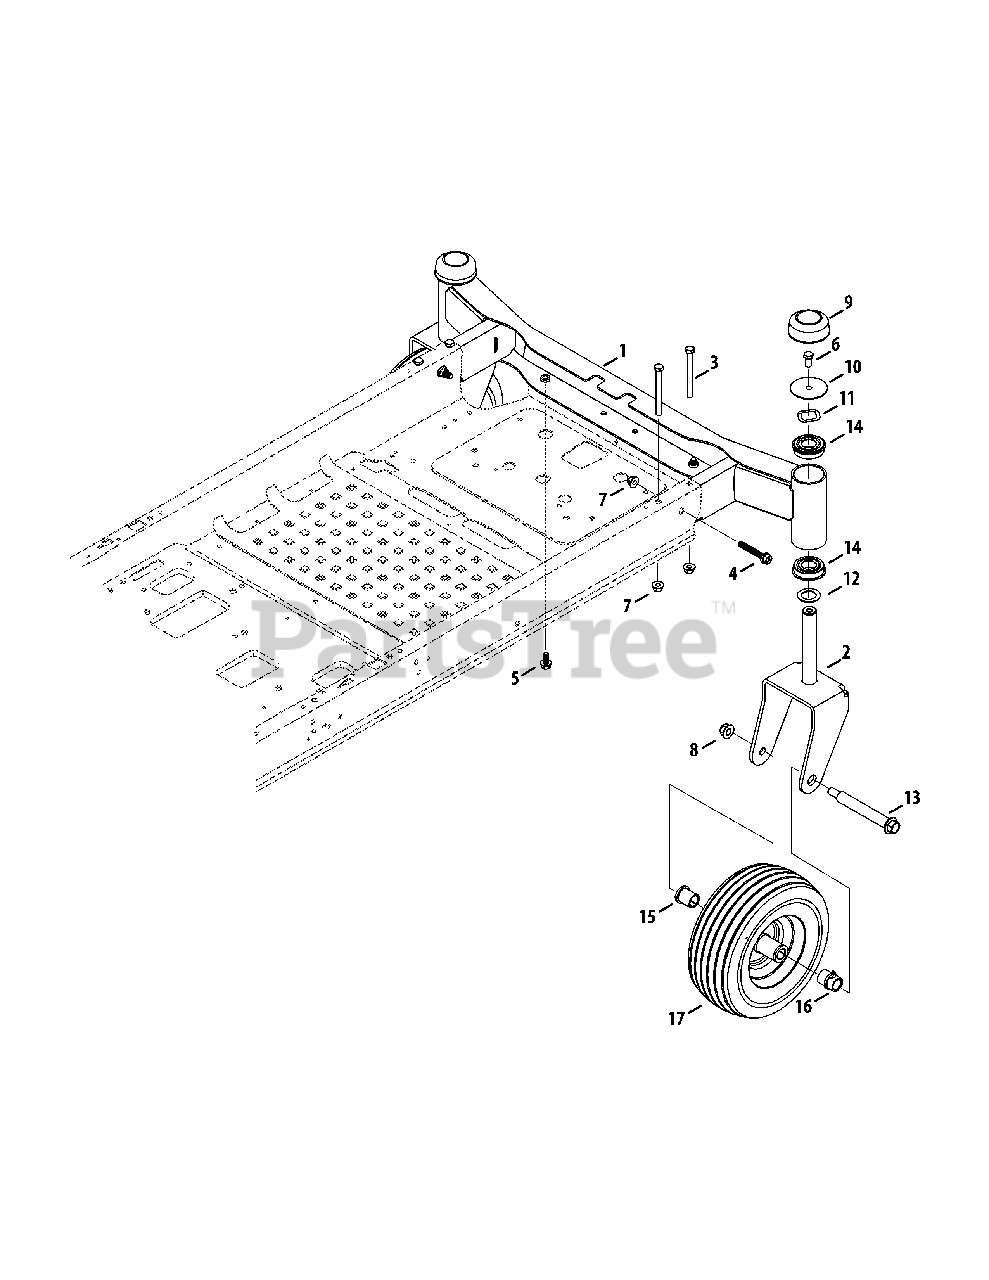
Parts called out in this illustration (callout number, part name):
1	Front Axle
2	Caster Wheel Bracket
3	Hex Cap Screw 3/8-16 x 3.75
4	Hex Flange Screw 3/8-16 x 2.00
5	Screw TT 3/8-16 x .750
6	Hex Cap Screw 3/8-16 x .750
7	Flange Lock Nut 3/8-16
8	Flange Lock Nut 1/2-13
10	Shoulder Spacer 2.50 x .02
11	Wave Washer 1.25 x 1.00 x .300
12	Flat Washer 1.010 x 1.56 x .060
13	Shoulder Screw 1/2-13
14	Ball Bearing
15	Flange Bearing .76 x 1.0 x 1.2
16	Flange Bearing .76 ID w/Lube Ftg.
17	Wheel Assembly 11.0 x 4.0 x 5.0
